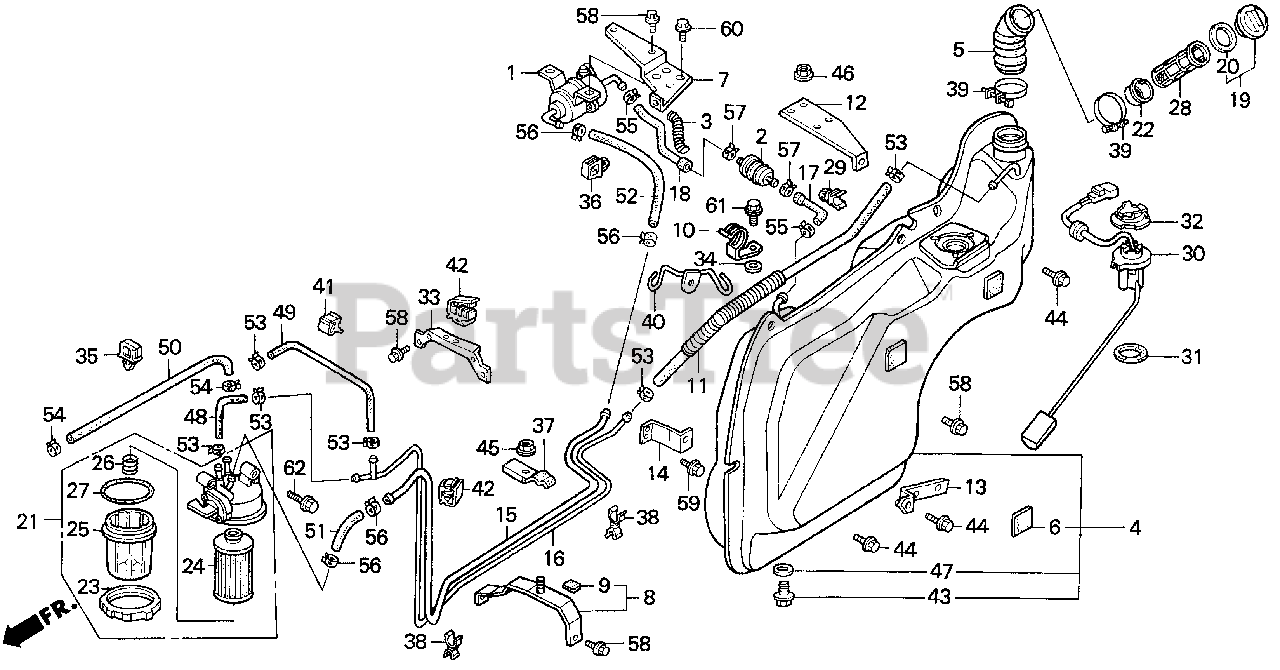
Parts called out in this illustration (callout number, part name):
1	PUMP ASSY., FUEL
2	FILTER, FUEL PUMP
3	SPRING, TUBE COVER (9MM)
4	TANK ASSY., FUEL
5	TUBE, FILLER NECK
6	RUBBER, TANK MOUNTING (A)
7	BRACKET, FEED PUMP
8	BASE, CLAMP
9	RUBBER, PIPE CUSHION
10	CLAMP, FUEL STRAINER
11	HOSE, FUEL RETURN
12	BRACKET, TANK & BODY MOUNTING
13	BRACKET A, FUEL TANK
14	BRACKET B, FUEL TANK
15	PIPE, FUEL SUPPLY
16	PIPE, FUEL RETURN
17	TUBE A, FUEL
18	TUBE B, FUEL
19	CAP, FUEL FILLER
20	GASKET, FUEL FILLER CAP
21	FILTER ASSY., FUEL
22	HOLDER, FUEL FILTER
25	CHAMBER, STRAINER
26	SPRING, COIL
28	FILTER, FUEL FILLER
29	CLIP, THROTTLE WIRE
31	GASKET, BASE
32	RETAINER, FUEL UNIT
33	BRACKET, RR. COVER
34	WASHER, PLAIN (8MM) (NOT AVAILABLE)
35	CLIP, HARNESS (15MM) (BLUE)
36	CLIP, WIRE HARNESS (13MM) (GRAY)
37	CLAMP, FUEL PIPE
38	CLAMP B, FUEL PIPE
39	CLIP, FILLER TUBE
40	CLAMP, FUEL HOSE
41	CLIP, CABLE (10MM)
42	CLIP, FUEL PIPE
43	BOLT, DRAIN PLUG (12MM)
44	BOLT-WASHER (8X16)
45	NUT, FLANGE (6MM)
46	NUT, FLANGE (10MM)
47	WASHER, DRAIN PLUG (12MM)
48	BULK HOSE, FUEL (4.5X3000) (4.5X120)
49	BULK HOSE, FUEL (4.5X3000) (4.5X305)
50	BULK HOSE, FUEL (5.5X8000) (5.5X320)
51	BULK HOSE, FUEL (7.5X3000) (7.3X110)
52	BULK HOSE, FUEL (7.5X3000) (7.5X235)
53	CLIP, TUBE (D8.5)
54	CLIP, TUBE (D10.5)
55	CLIP, TUBE (D12)
56	CLIP, TUBE (D12.5)
57	CLIP, TUBE (D13)
58	BOLT, FLANGE (6X12)
59	BOLT, FLANGE (8X16)
60	BOLT, FLANGE (8X20)
61	BOLT, FLANGE (8X22)
62	BOLT, FLANGE (8X30)
